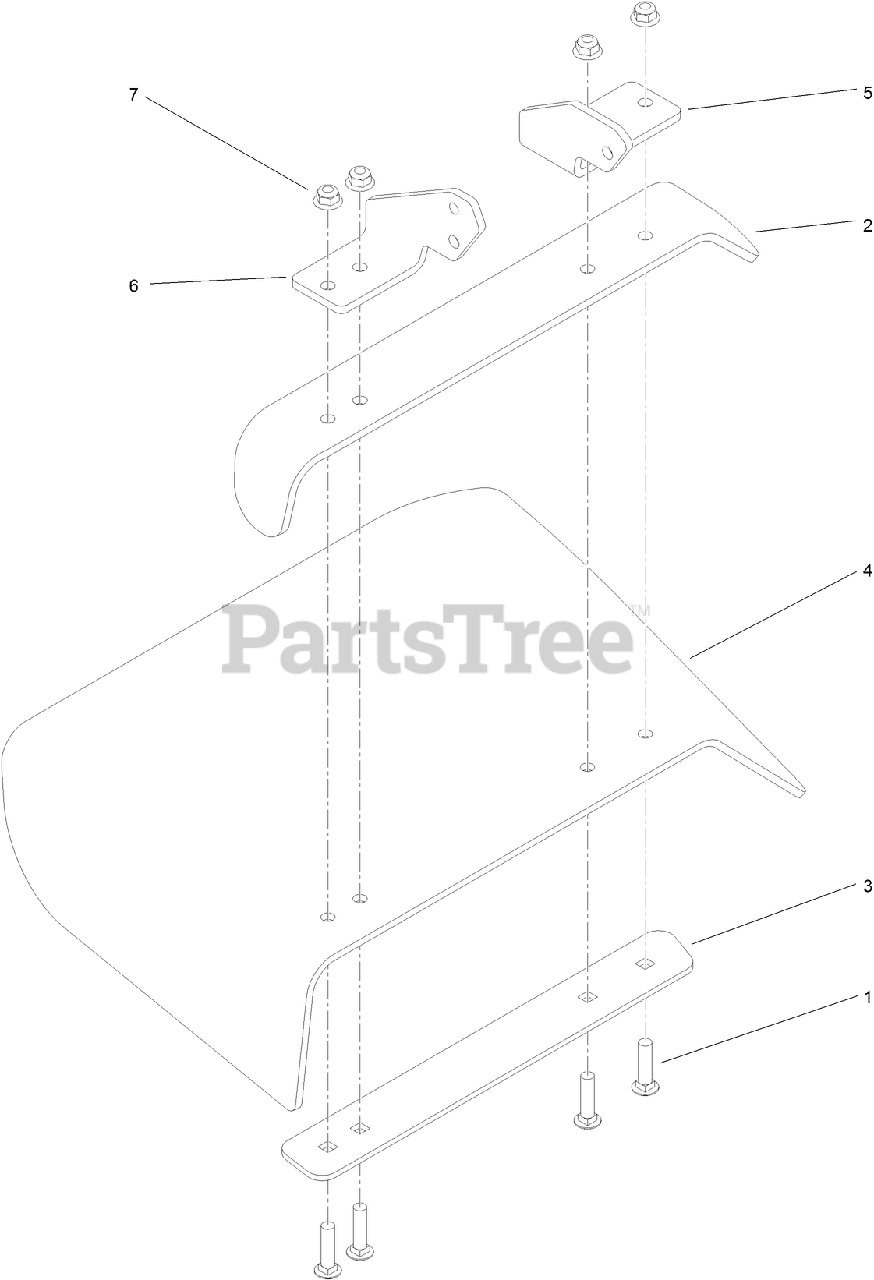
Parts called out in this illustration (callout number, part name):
1	SCREW-CARR
2	DEFLECTOR
3	STRAP-DISCHARGE
4	DEFLECTOR-RUBBER
5	PLATE-HINGE, REAR
6	PLATE-HINGE, FRONT
7	NUT-HF, NI
